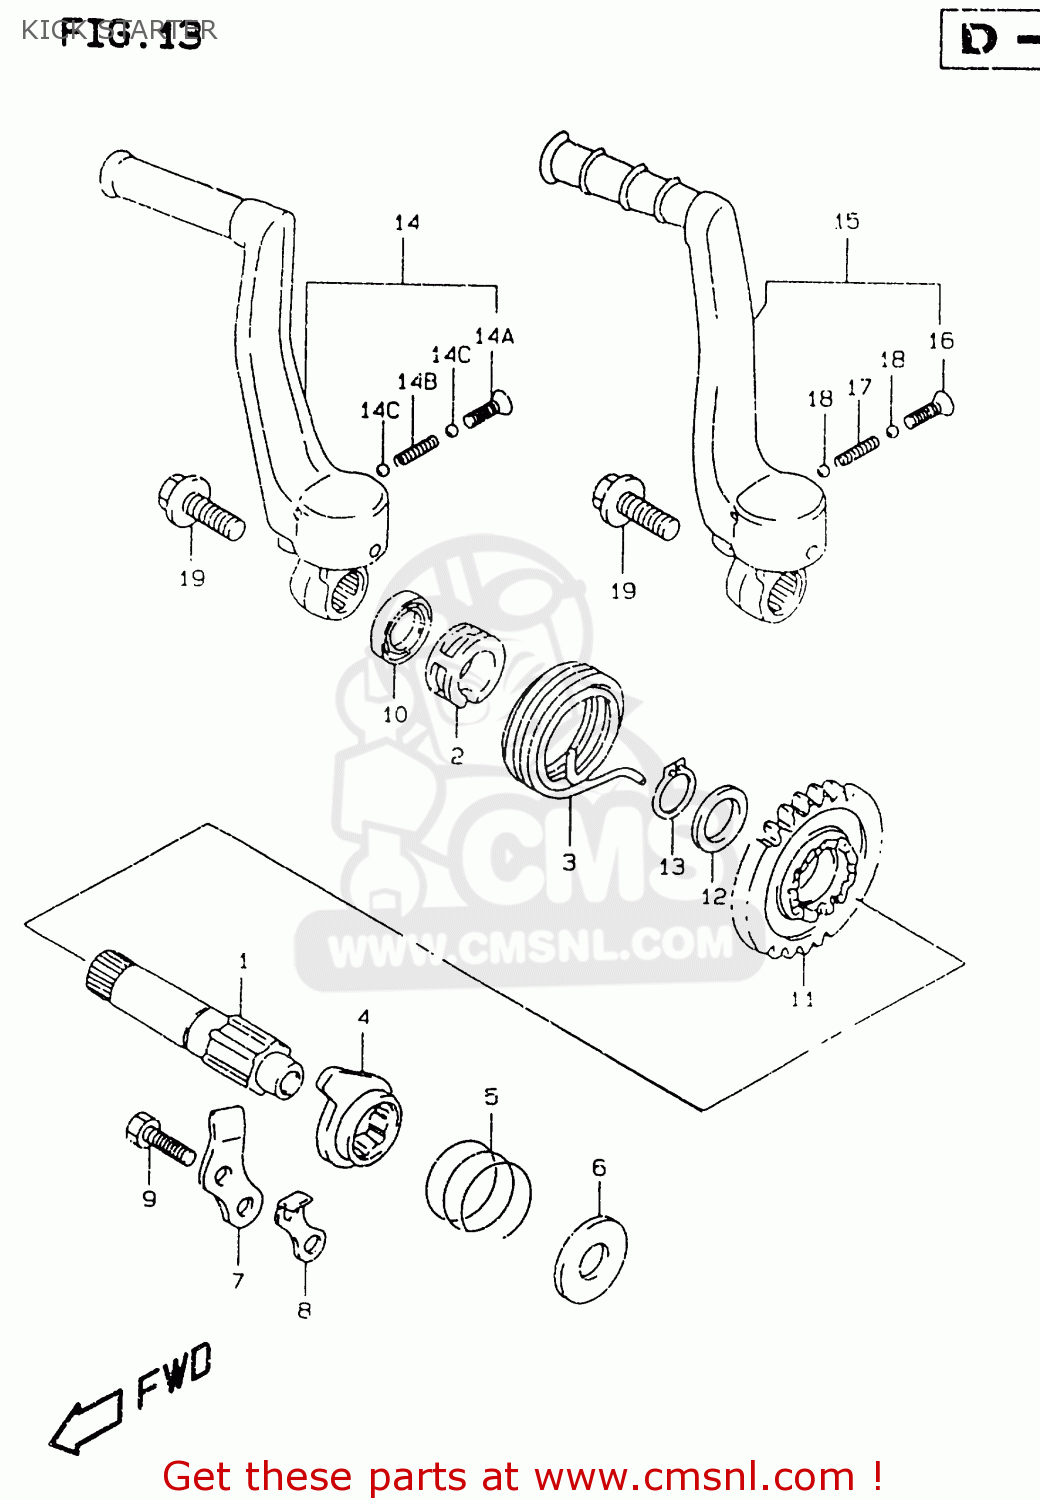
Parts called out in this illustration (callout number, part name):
1	SHAFT,KICK STARTER
2	GUIDE,KICK STARTER SFT SPRING
3	SPRING
4	STARTER,KICK
5	SPRING
6	WASHER
7	GUIDE,KICK STARTER
8	STOPPER,KICK STARTER
9	BOLT
10	SEAL,OIL(15.8X24X5)
11	GEAR,KICK STARTER DRIVE
12	WASHER
13	CIRCLIP 16MM
14	LEVER ASSEMBLY,KICK STARTER
14A	SCREW(6X27.5)
14B	SPRING
14C	BALL
15	LEVER ASSY,KICK STARTER
16	SCREW(6X27.5)
17	SPRING
18	BALL
19	BOLT(8X14)
